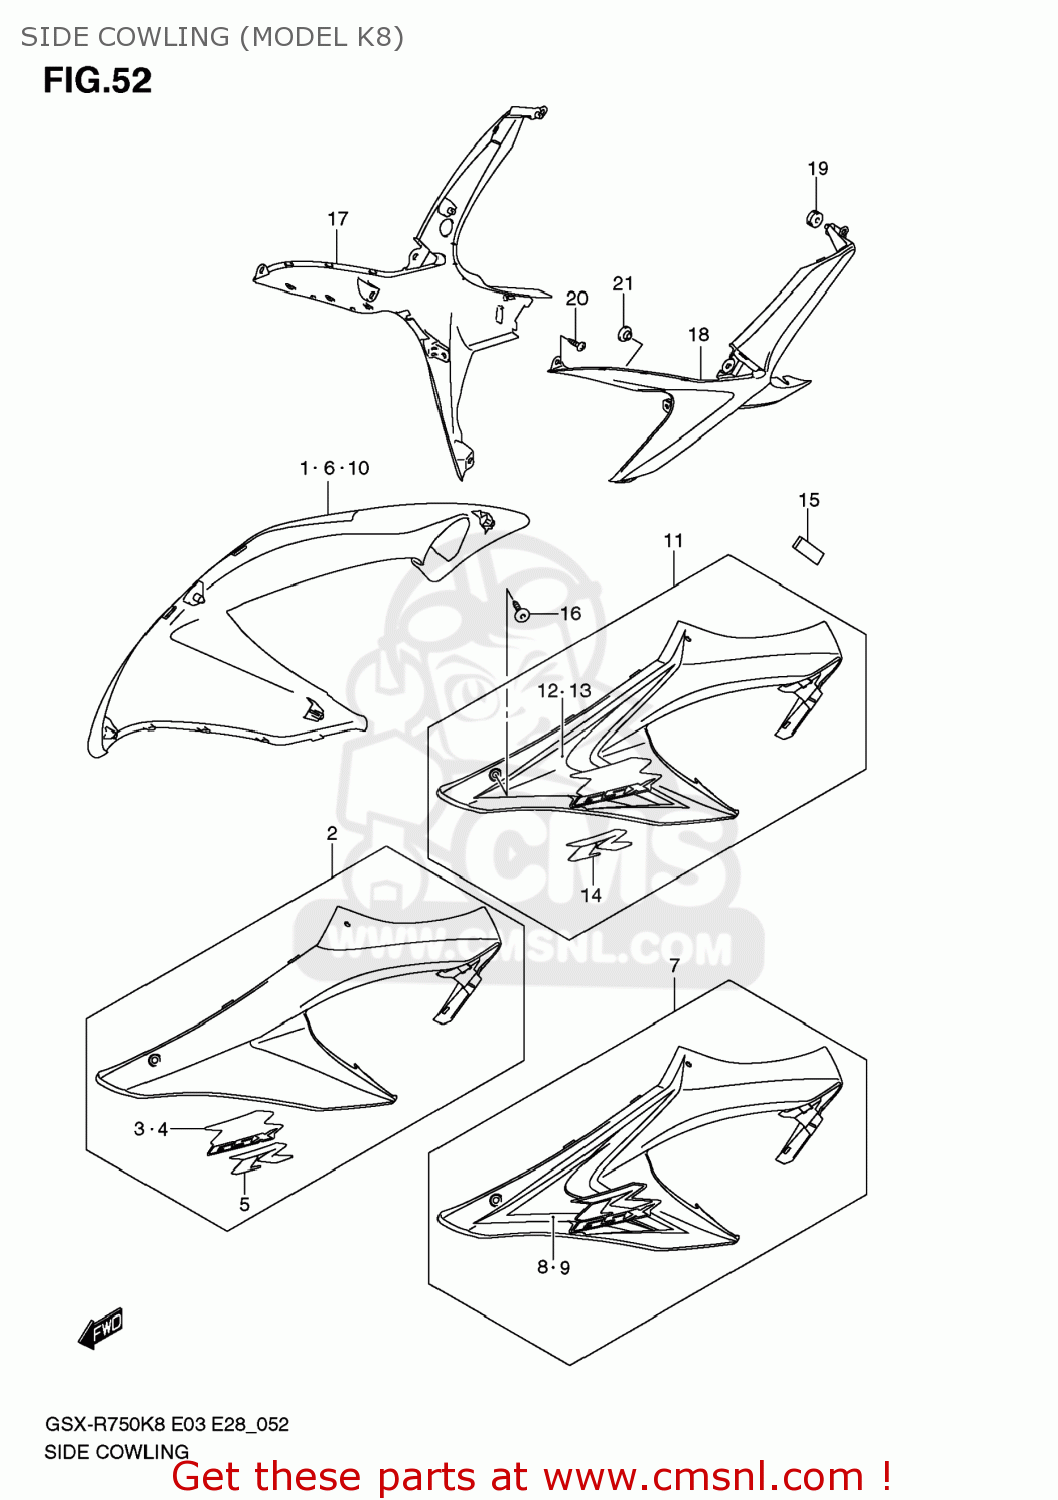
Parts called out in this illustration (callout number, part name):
1	COWLING,SIDE,R(BLACK)
2	COWLING,SIDE,L(BLACK)
3	EMBLEM,GSXR,R
4	EMBLEM,GSXR,L
5	EMBLEM,R
6	COWLING,SIDE,R(BLUE)
7	COWLING,SIDE,L(BLUE)
8	TAPE,COWL SIDE,R
9	TAPE,COWL SIDE,L
10	COWLING,SIDE,R(BLACK)
11	COWLING,SIDE,L(BLACK)
12	TAPE,COWL SIDE,R
13	TAPE,COWL SIDE,L
14	EMBLEM,R
15	CUSHION,SIDE COWL
16	SCREW(5X16)
17	COVER,UNDER COWL,R
18	COVER,UNDER COWL,L
19	CUSHION
20	SCREW
21	CUSHION
